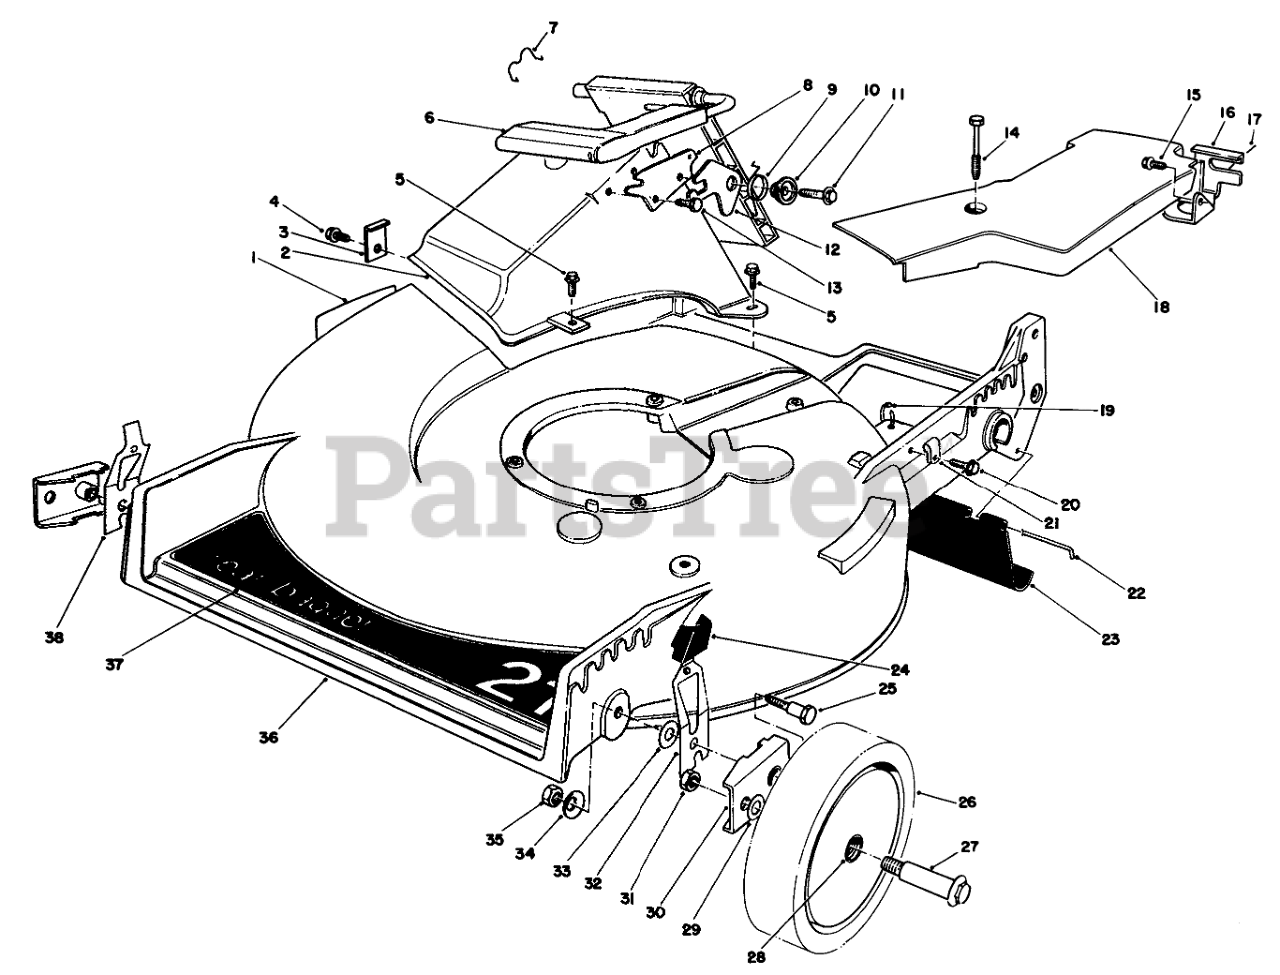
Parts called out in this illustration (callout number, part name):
1	DECAL-DANGER
2	Tunnel Discharge
3	TUNNEL CLIP
4	SCREW
5	SCREW-HWH
6	Discharge Door Assembly
7	DOOR RET SPRING
8	DOOR LATCH PLATE
9	TORSION SPRING
10	DOOR SPACER
11	SCREW-HWH
12	SAFETY LATCH
13	SCREW-PLASTITE
14	SCREW-HHFTF
15	SCREW-HWHTF
16	Bracket-Traction Adj.
17	RETAINER-CABLE
18	Cover-Belt
19	TIE-CABLE
20	SCREW
21	CLAMP-CABLE
22	ROD-SHIELD
23	SHIELD-TRAILING
24	KNOB-ARM
25	PIVOT SCREW
26	Wheel & Tire Assembly (Incl. Ref. #28)
27	BOLT-WHEEL
28	BUSHING
29	WASHER
30	HP PIVOT ARM ASM
31	Nut
32	L. HP SPRING ARM ASM
33	WASHER-PIVOT
34	WASHER-BELLEVILLE
35	NUT-LOCK, NI
36	Housing (Incl. Ref. #1)
37	DECK DECAL
38	R HP SPRING ARM ASM
